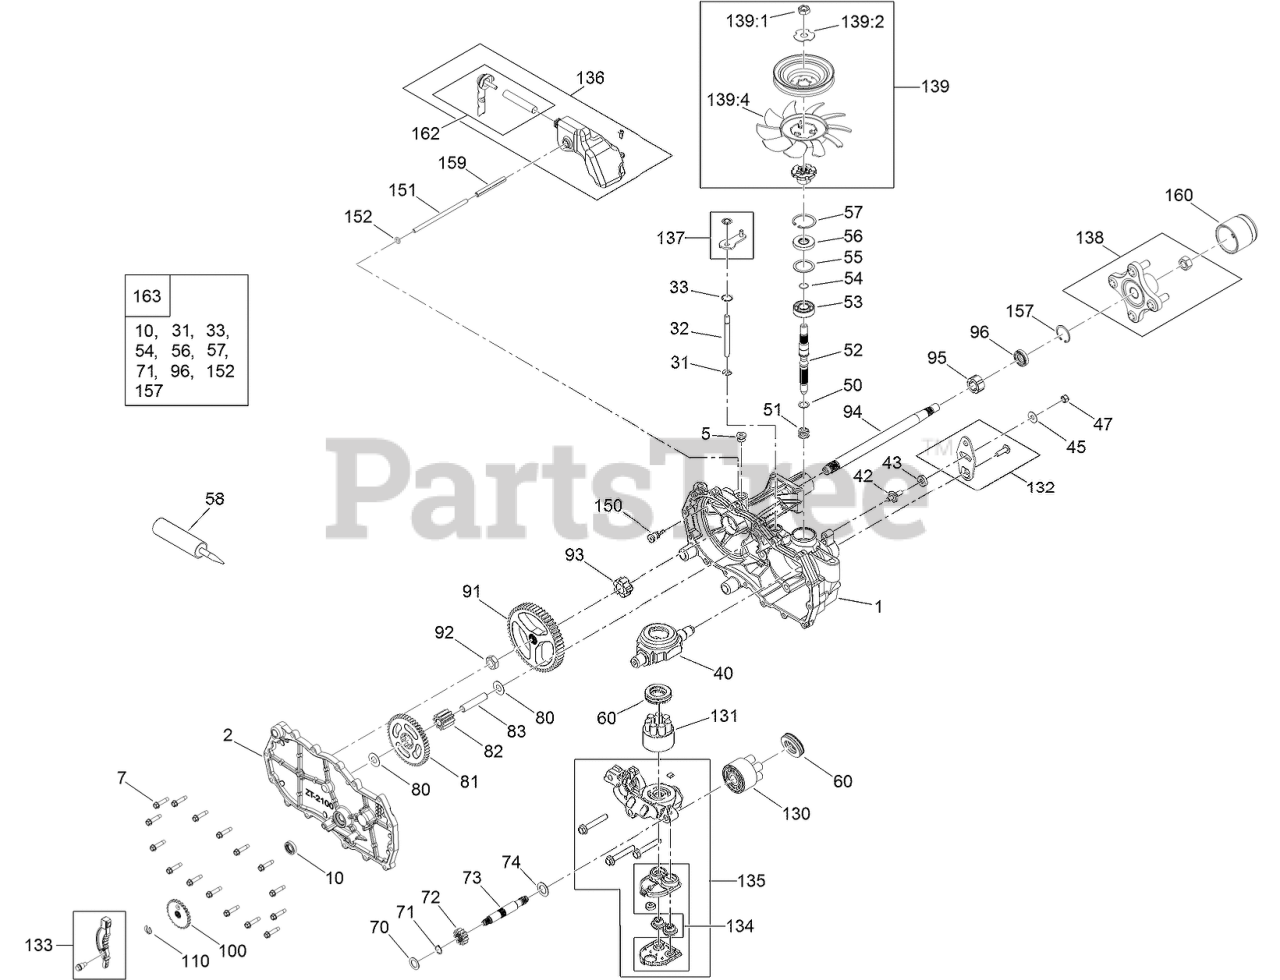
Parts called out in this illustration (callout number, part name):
1	MAIN HOUSING ASM
2	HOUSING SIDE KIT
5	PLUG-THREAD, STRAIGHT
7	SCREW-HHF
10	Seal-Lip
31	RING-RETAINING, EXTERNAL
32	ROD-BYPASS
33	RING-RETAINING, INTERNAL
40	SWASHPLATE-TRUNNION
43	PUCK-FRICTION
45	WASHER
50	WASHER
51	SPRING-BLOCK
52	SHAFT-INPUT
53	BEARING-BALL
54	RING-RETAINING
55	SPACER
56	SEAL-LIP
57	RING-RETAINING
58	SEALANT
60	BEARING-THRUST
70	WASHER-FLAT
71	RING-RETAINING
72	GEAR-PINNION, 13T
73	SHAFT-MOTOR
74	WASHER
80	WASHER
81	GEAR-10T/48T
82	GEAR-JACKSHAFT, 10T
83	PIN-JACKSHAFT
91	GEAR-BULL
92	NUT-HJ
93	BUSHING-INBOARD
94	SHAFT-AXLE
95	BEARING-SLEEVE
100	DISC-BRAKE, COG
110	RING-RETAINING, EXTERNAL
130	CYLINDER BLOCK KIT
131	PUMP BLOCK ASM
132	CONTROL ARM KIT
133	BRAKE ARM KIT
134	CENTER SECTION FILTER KIT
135	FILTER KIT
136	LH EXPANSION TANK KIT
137	BYPASS ARM KIT
138	HUB KIT
139	FAN AND PULLEY KIT
139:1	NUT-HJ
139:2	WASHER-SLOTTED
139:4	FAN 7.0 X 10 BLADE
150	FITTING-SAE
152	O-RING
159	CASE-TUBE
160	CAP-AXLE
162	BREATHER ASM KIT
163	SEAL AND RING KIT
